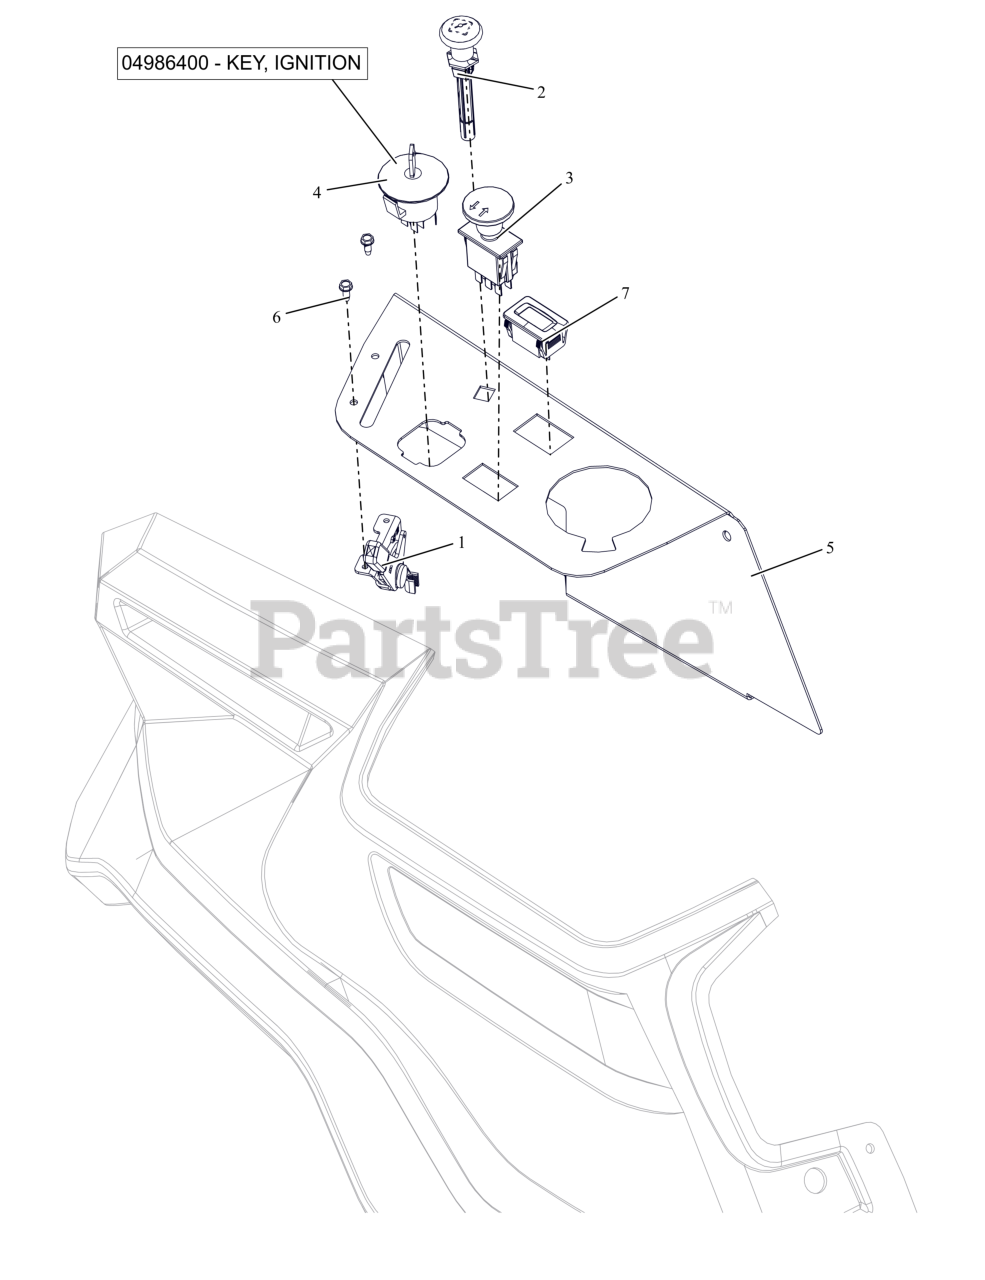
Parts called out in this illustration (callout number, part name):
1	CABLE - THROTTLE CONTROL
2	CABLE - CHOKE, SNAP-IN
3	SWITCH, CLUTCH (YELLOW)
4	KEYSWITCH-IGNITION 4 POS
4	KEY, IGNITION
5	PANEL, RIGHT SIDE FENDER MOUNT
6	SCR,TAP #10-24X.50 HWH TR ZCC
7	HOUR METER
